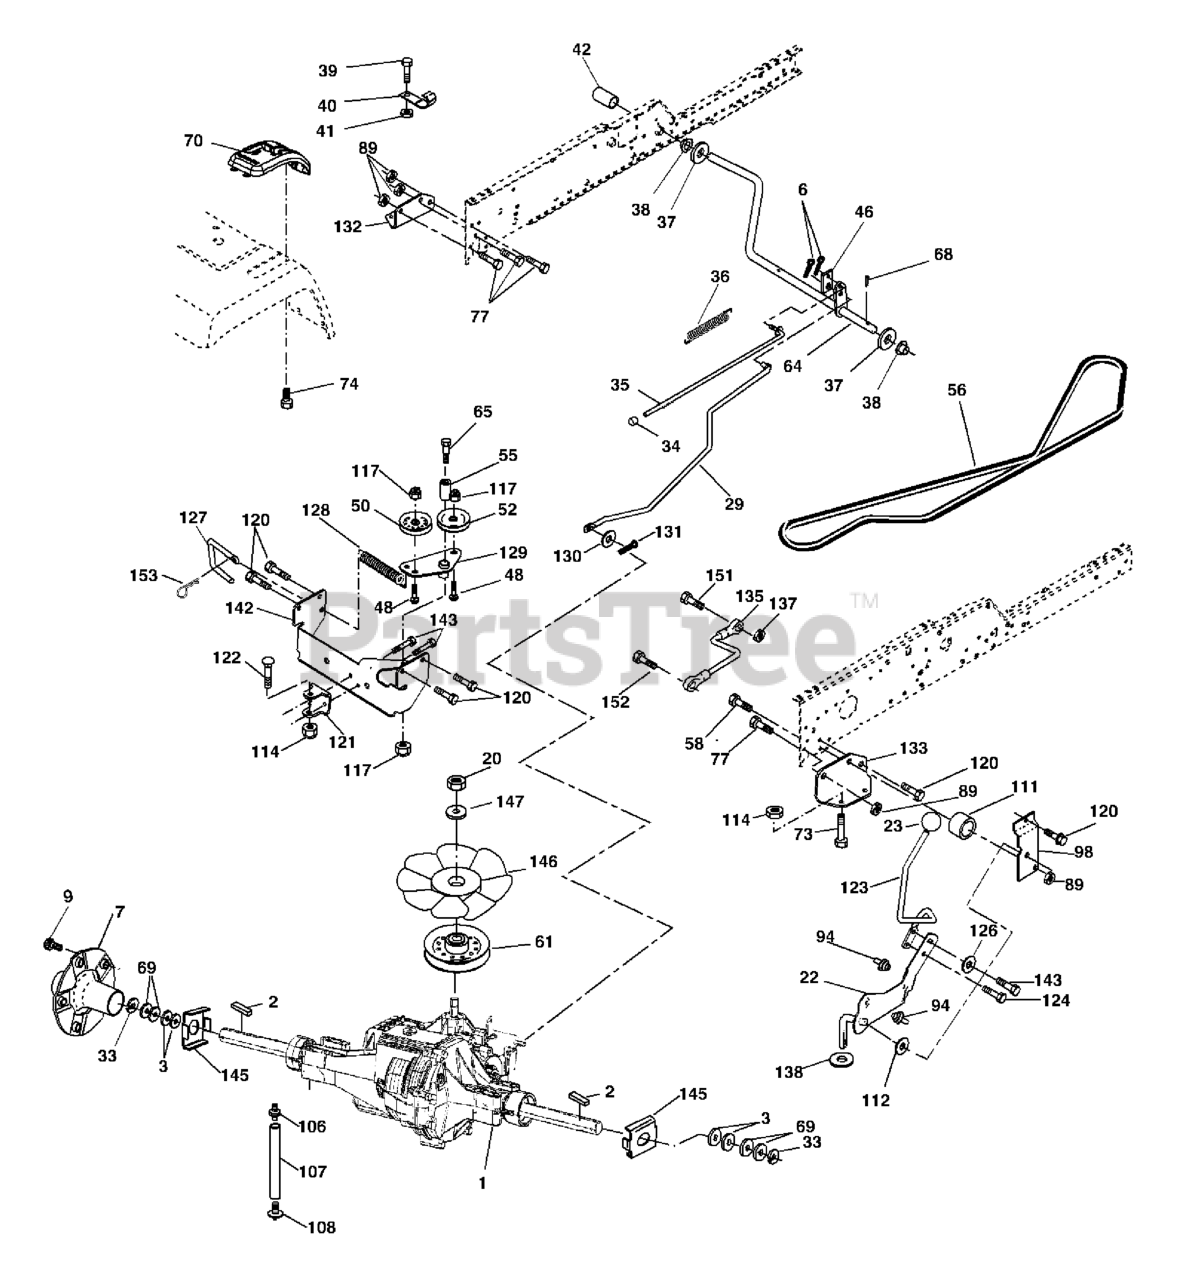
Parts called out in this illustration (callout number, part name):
2	KEY 1/4 X 2.5
6	COTTER PIN
7	HUB ASMBLY
9	HUB BOLT
20	NUT.HEX.1/2-20
22	LOWER SHIFT LEVER ASM
23	KNOB.DELUXE.(PISTOL.GRIP).BLAC
29	BRAKE, ROD
33	E RING HYT
34	PLUNGER CAP
35	PARKING BRAKE ROD
36	SPRING DRIVE GROUND
39	Screw, Fin. #10-24 x 1
40	ACTUATOR INTERLOCK SWITCH
41	Nut Centerlock 10-24 unc
42	PEDAL COVER T
46	RETAINER SPRING
50	FLAT IDLER PULLEY
52	IDLER PULLEY
55	BEARING LT (2 2)
56	BELT, V GROUND DRIVE
58	BOLT.HEX.7/16-14.FINISHED
61	PULLEY, TRANSAXLE
64	SHAFT.ASM.PEDAL.BRAKE
65	BOLT.SHLDR.3/8-16
68	ROLL PIN STD
70	CONSOLE.SHIFT
73	BOLT HEX FLGHD 5/16-18X3 GR. 5
74	SCREW.HI-LO.CONSOLE
77	BOLT FIN HEX 7/16-14 X 1
89	Nut Crownlock 7/16-14 unc
94	FASTENER.XMAS.TREE
98	SHIFT BRACKET
106	O-RING KIT 70110
107	LINE.VENT.HYDRO-GEAR
108	CAP, VENT ASSY
111	SPACER SHIFT LEVER VGTH
112	WASHER NYLON HIGH TEMP
114	NUT.71038.31-18.HEX.NYLOCK
117	NUT LOCK FLG 3/8-16 UNC
120	SCREW, 3/8-16X3/4
121	BRACKET STRAP TORQUE
122	BOLT.5/16-18X2.5
124	BOLT.SHOULDER.5/16-18X
126	WASHER.SRRTD.5/16
127	LINK CONTROL CLUTCH
128	SPRING DRIVE GRND
129	BRACKET ARM IDLER TENSIONING
131	COTTER PIN
132	BRACKET MTG HYDRO 3500 LH VGT
133	BRACKET MTG HYDRO 3500 RH VGT
135	LINK ASM CONTROL HYDRO 3500
138	THRUST WASHER
142	STRAP TORQUE HT-3500
143	SCREW
145	WASHER.AXLE.FLANGE.HG-3000
146	FAN 7" HYDRO
151	BOLT
152	BOLT HEX 5/16X1 W/PATCH
153	RETAINER M
